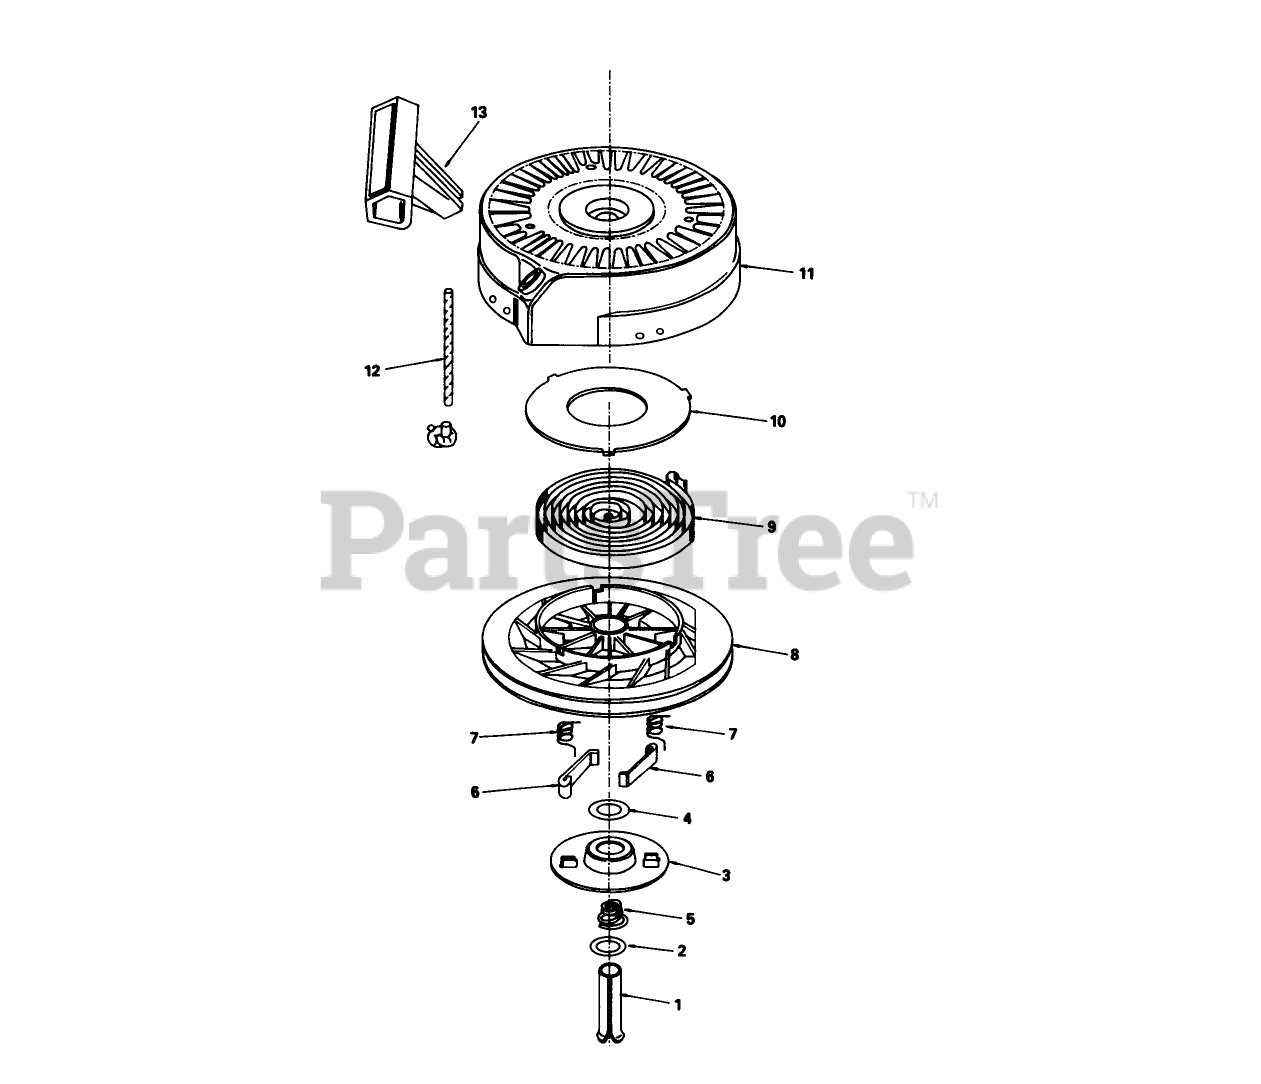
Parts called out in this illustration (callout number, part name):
1	Pin, Spring (Incl. Ref. #7)
2	Washer
3	Retainer
4	Washer
5	Brake Spring
6	Dog-Starter
7	Spring-Dog
8	Pulley
9	Rewind Spring
10	Cover-Spring
11	Housing-Starter
12	Rope-Starter (98 cut to length)
13	Handle-Starter
